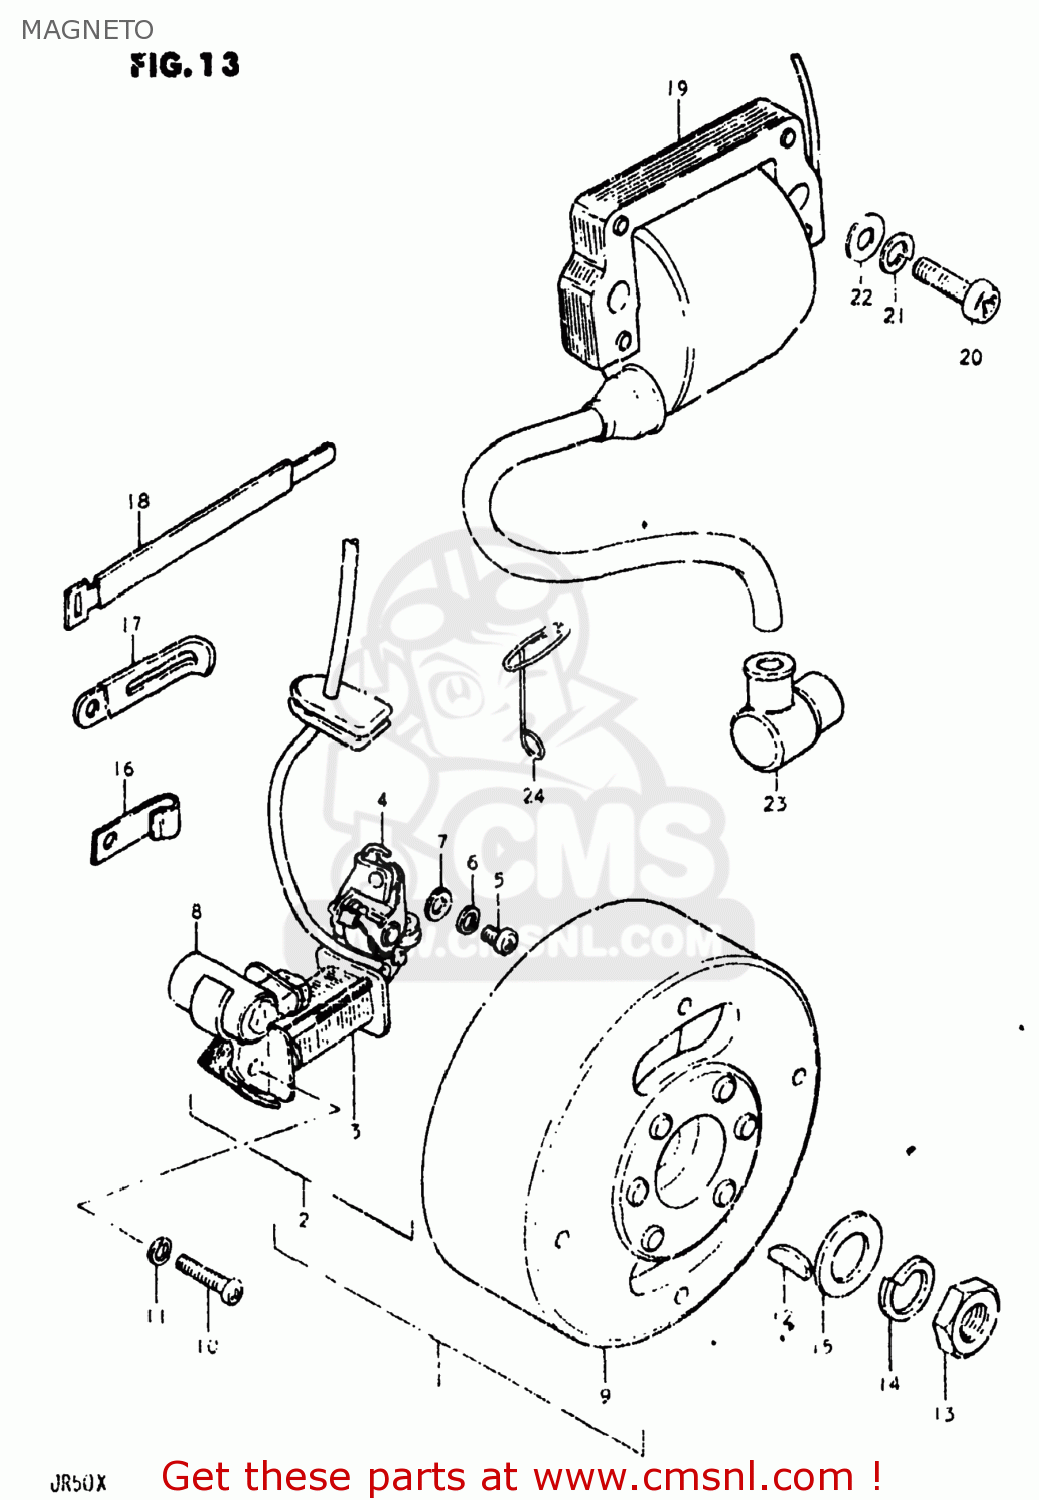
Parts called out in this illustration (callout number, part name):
1	MAGNETO ASSEMBLY
2	STATOR ASSEMBLY
3	COIL ASSY,IGNITION PRIMARY
4	POINT ASSY,CONTACT
5	SCREW(4X10)
6	LOCK WASHER
7	WASHER
8	CONDENSER,MAGNETO
9	ROTOR ASSEMBLY
10	SCREW 4X25
11	LOCK WASHER
12	KEY
13	NUT (10MM)
14	LOCK WASHER
15	WASHER
16	CLAMP
17	CLAMP L:35
18	CLAMP
19	COIL ASSEMBLY,IGNITION
20	SCREW
21	LOCK WASHER
22	WASHER
23	CAP,SPARK PLUG
24	CLIP
